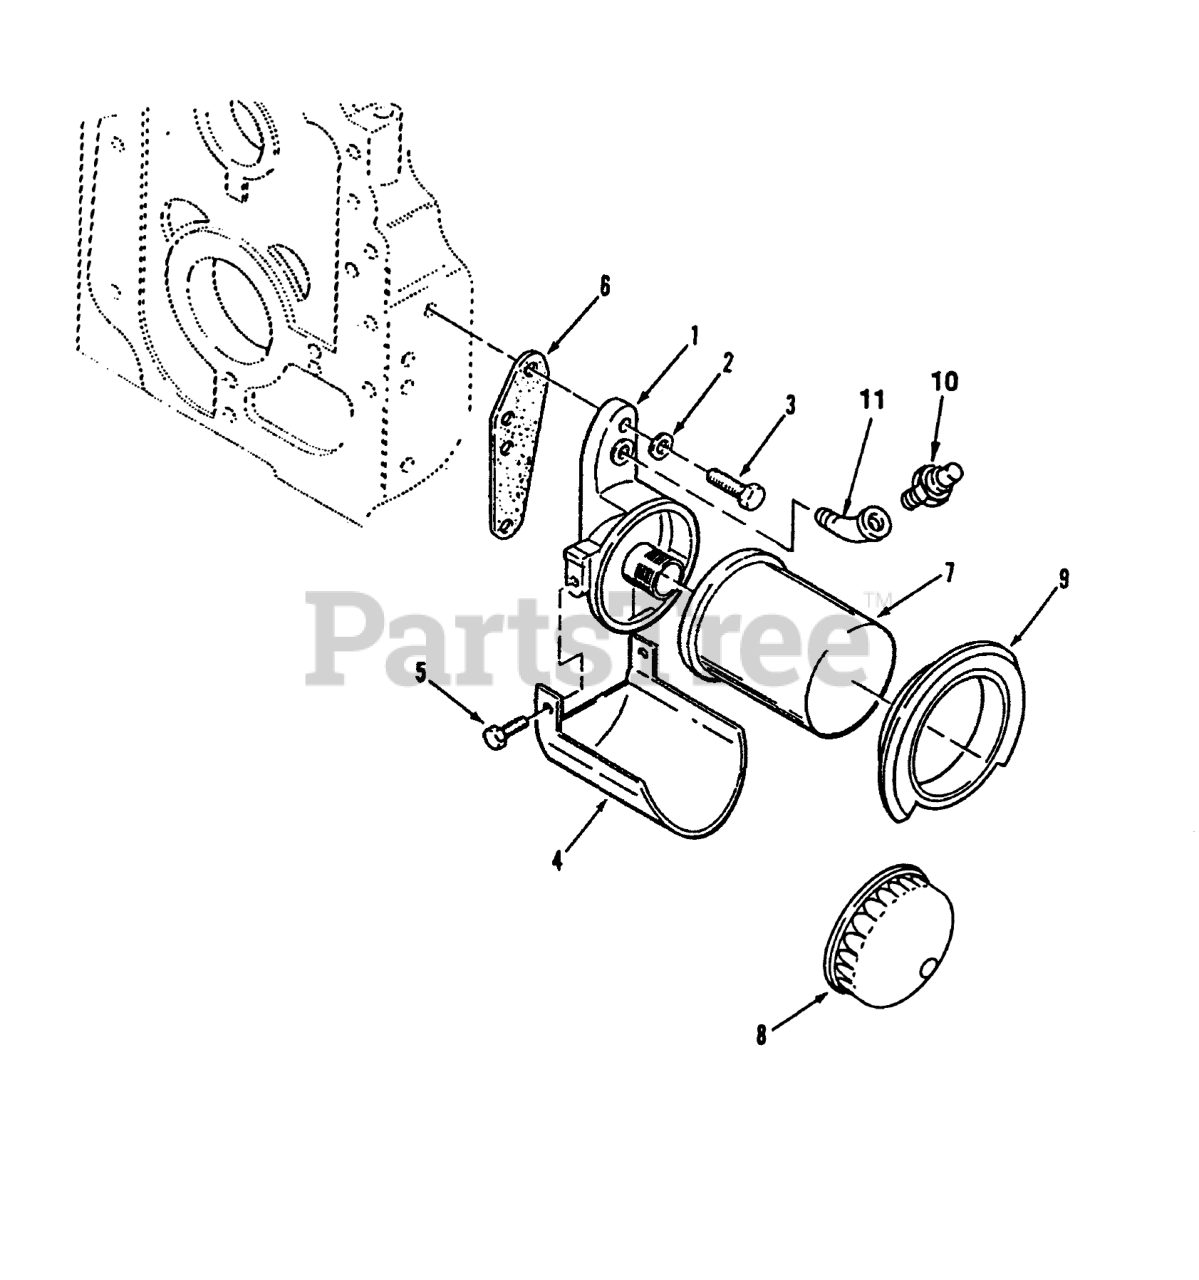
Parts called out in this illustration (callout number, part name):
1	ADAPTER-OIL FILTER
2	WASHER
3	HHCS 5/16-18 X 1
4	OIL-FILTER DRAIN
5	SCREW-HH
6	Gasket
7	OIL FILTER
8	Wrench
9	GASKET - AIR SEAL
10	SWITCH
11	45 DEG STREET ELBOW
